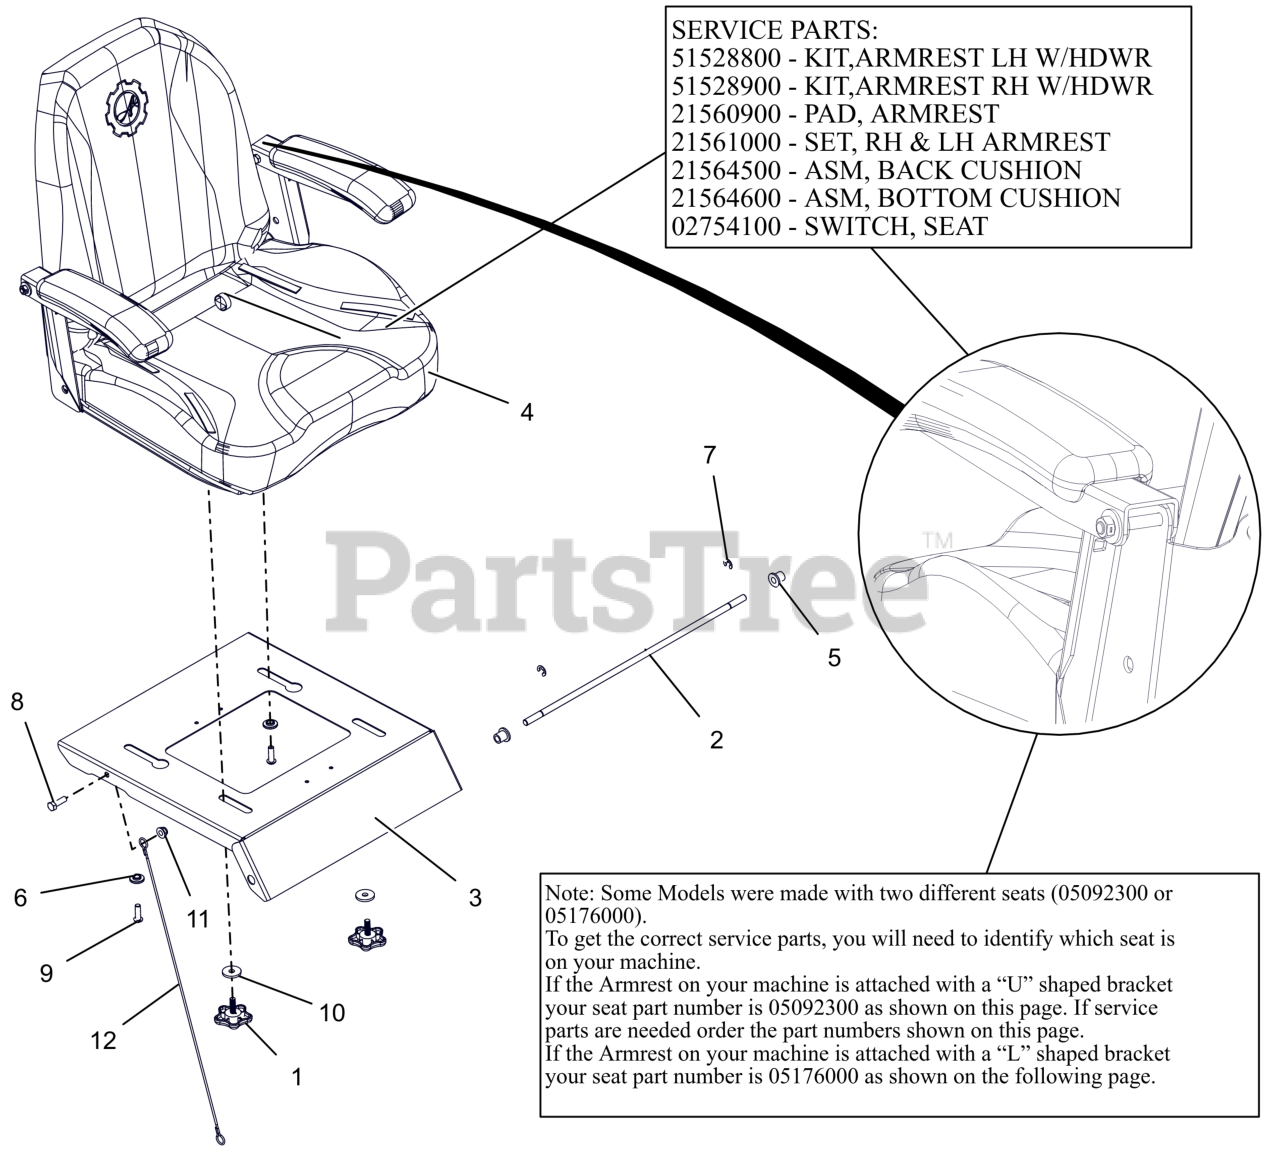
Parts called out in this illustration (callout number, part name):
1	KNOB, WING STUDDED
2	ROD, SEAT PIVOT
3	PLATE, SEAT (FASTENER SLIDE)
4	SEAT, IKON
4	KIT, ARMREST LH
4	KIT, ARMREST RH
4	PAD, ARMREST (HARD)
4	SET,RH & LH ARMREST -HARD
4	ASM, BACK CUSHION-ARIENS X
4	ASM, BOTTOM CUSHION-ARIENS X
4	SWITCH- SNAP MTG N.O.
5	BSHG-FLG .38X.580X.667X.750
6	BSHG, FLG .312X.499X.23X.88
7	RG-RTNG-EXT .375X.035 TYP E
8	BLT,HEX .31-18X1.00 G5 ZCC
9	BLT,SHCS-BTN .31-18X1.00 ZCC
10	WSHR, FLT .340X1.125X.135 ZCC
11	NUT,LK-NYL-FLG .31-18 G5ZC120
12	LANYARD, SEAT CABLE .093X19.5
